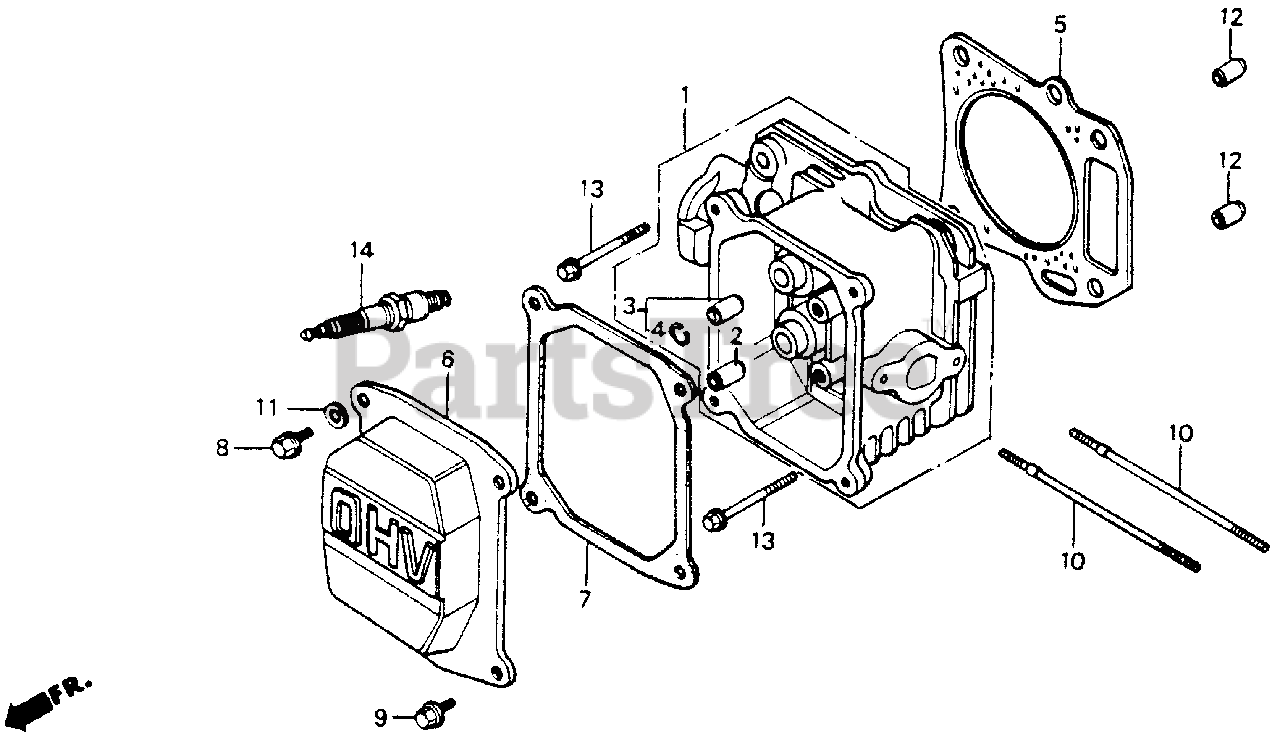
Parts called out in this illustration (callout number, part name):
1	CYLINDER HEAD
1	CYLINDER HEAD (USA)
2	GUIDE, VALVE (OS)
3	GUIDE, EX. VALVE (OS)
4	CLIP, VALVE GUIDE Use from Engine SN 1231803.
5	GASKET, CYLINDER HEAD
6	COVER, HEAD
7	GASKET, CYLINDER HEAD COVER
8	BOLT, FLANGE (6X14)
9	BOLT, FLANGE (6X13)
10	BOLT, STUD (6X109)
11	WASHER (6X17)
12	PIN A, DOWEL (10X16)
13	BOLT, FLANGE (8X45)
14	SPARK PLUG (W14EPR-U) (DENSO)
14	SPARK PLUG (BP4ES) (NGK)
14	SPARK PLUG (BP5ES) (NGK)
14	SPARK PLUG (W16EP-U) (DENSO)
14	SPARK PLUG (BP6ES) (NGK)
14	SPARK PLUG (W20EP-U) (DENSO)
